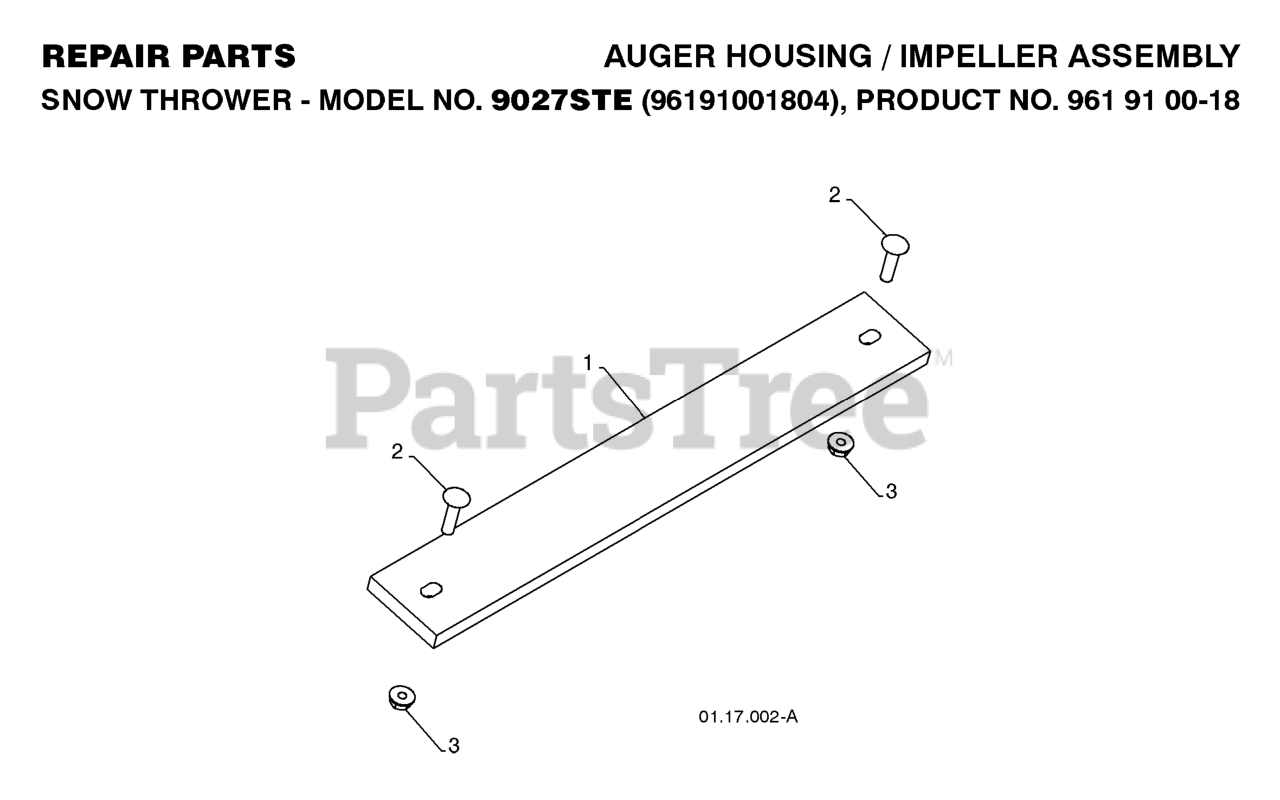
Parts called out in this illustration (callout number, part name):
1	WEIGHT,AUGER HOUSING 27 (2 2MC
2	BOLT.CARRIAGE.5/16-18
3	NUT.LOCK.5/16-18
